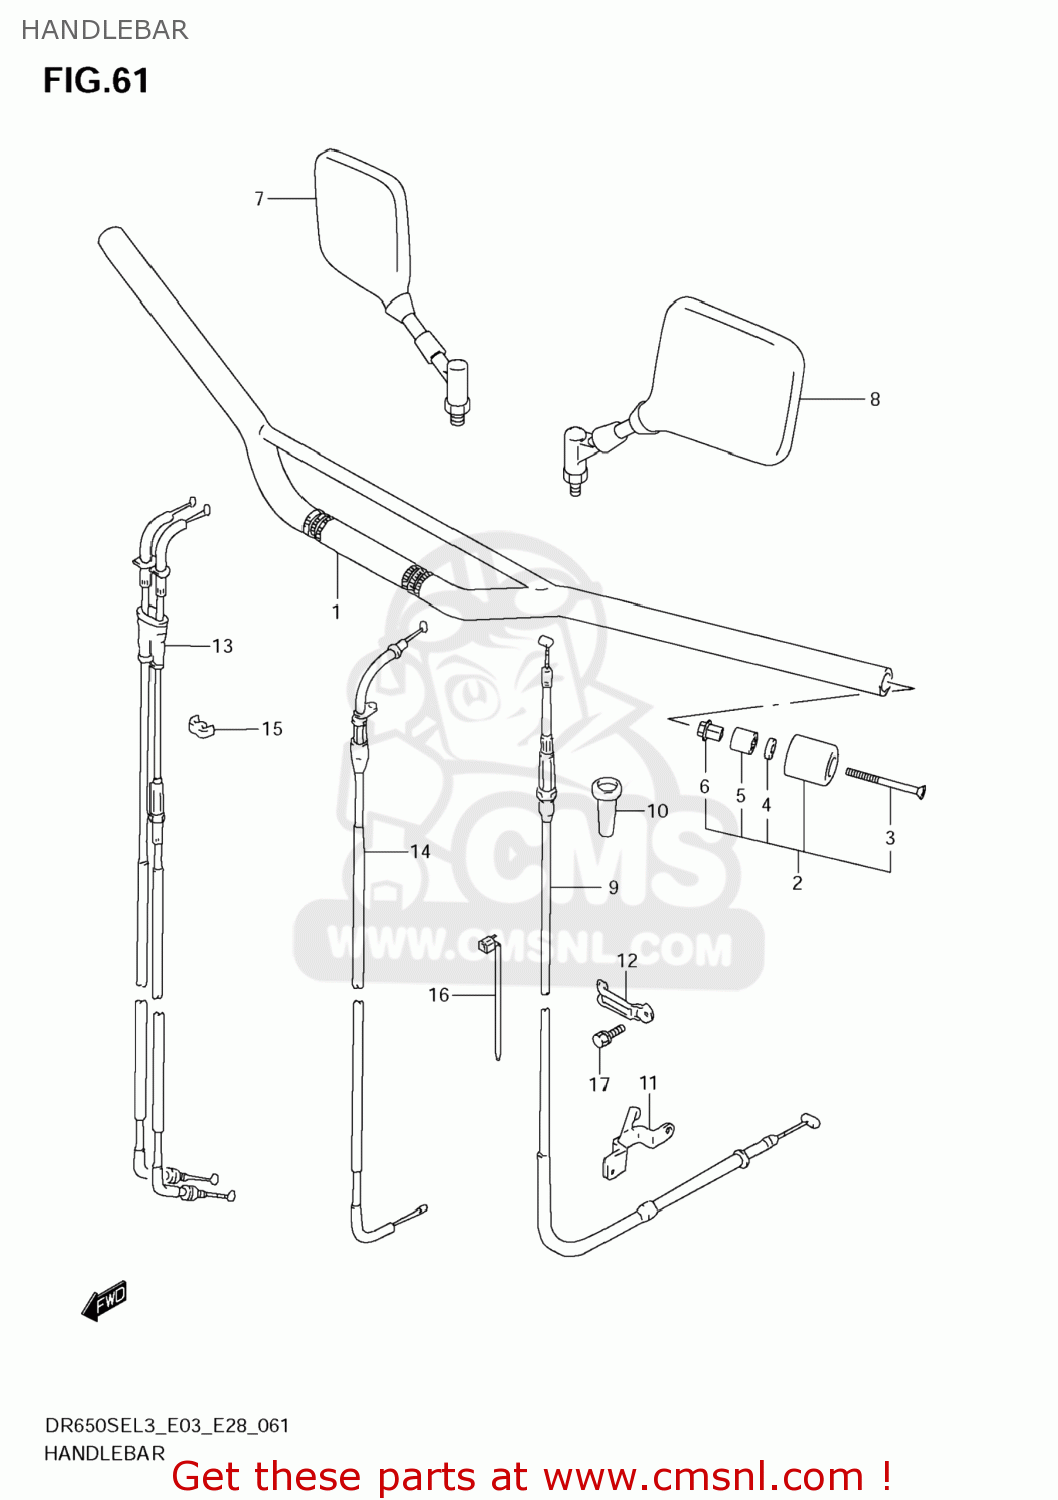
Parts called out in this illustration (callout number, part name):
1	HANDLEBAR(BLACK)
2	BALANCER SET,HANDLEBAR
3	SCREW
4	WASHER(6.5X16X4)
5	EXPANDER,HANDLE BALANCER
6	NUT,HANDLE BALANCER
7	MIRROR ASSY,RR VIEW,R
8	MIRROR ASSY,RR VIEW,L
9	CABLE ASSY,CLUTCH
10	BOOT,CLUTCH CABLE
11	STOPPER,CLUTCH CABLE
12	CLAMP
13	CABLE ASSY,THROTTLE
14	CABLE,STARTER
15	CLIP
16	CLAMP(L:235)
17	BOLT
